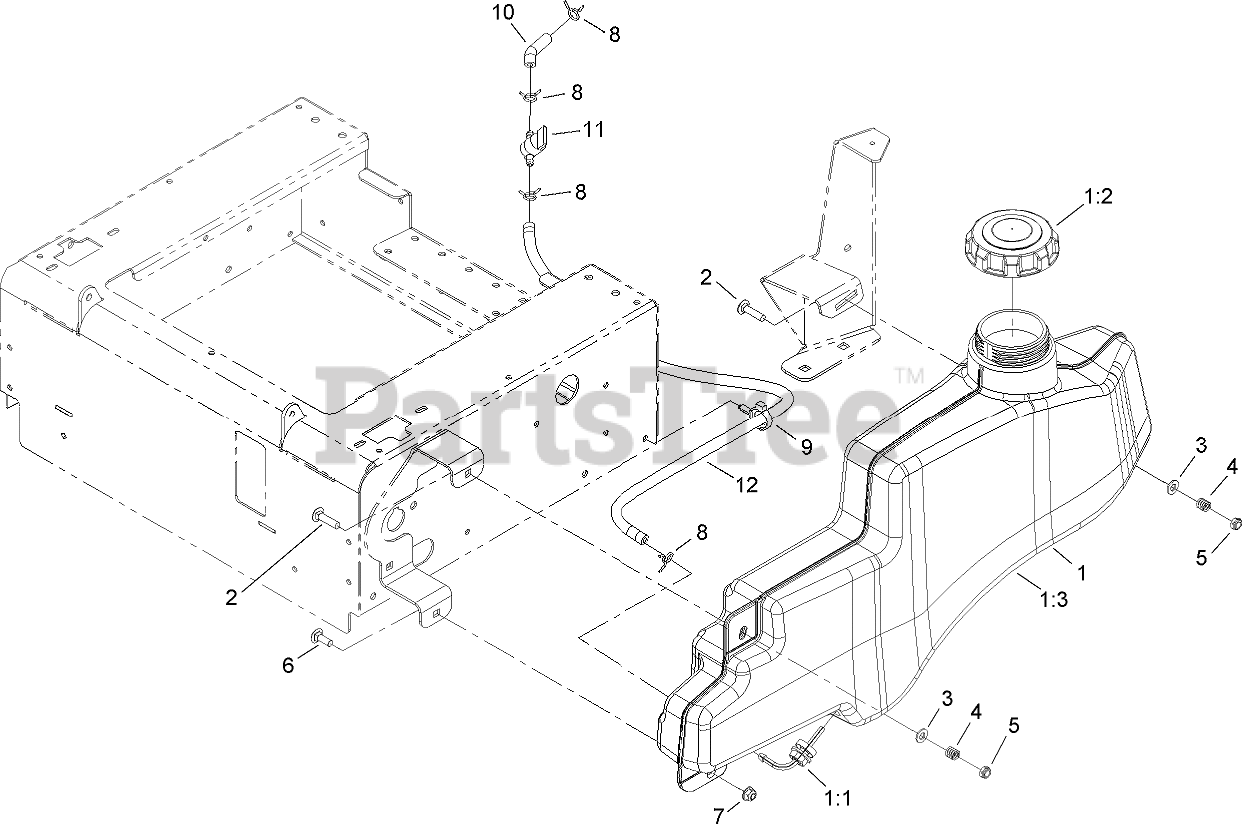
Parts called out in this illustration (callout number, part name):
1	FUEL TANK ASM
1:1	FITTING-FUEL, BULKHEAD
1:2	CAP-FUEL, GAS
1:3	TANK-FUEL
2	SCREW-CARR
3	WASHER-PLAIN
4	SPRING-TANK, FUEL
5	NUT-LOCK, NI
6	SCREW-CARR
7	NUT-HF, NI
9	CLAMP-HOSE
10	HOSE-FUEL
11	VALVE-FUEL
12	HOSE-FUEL
